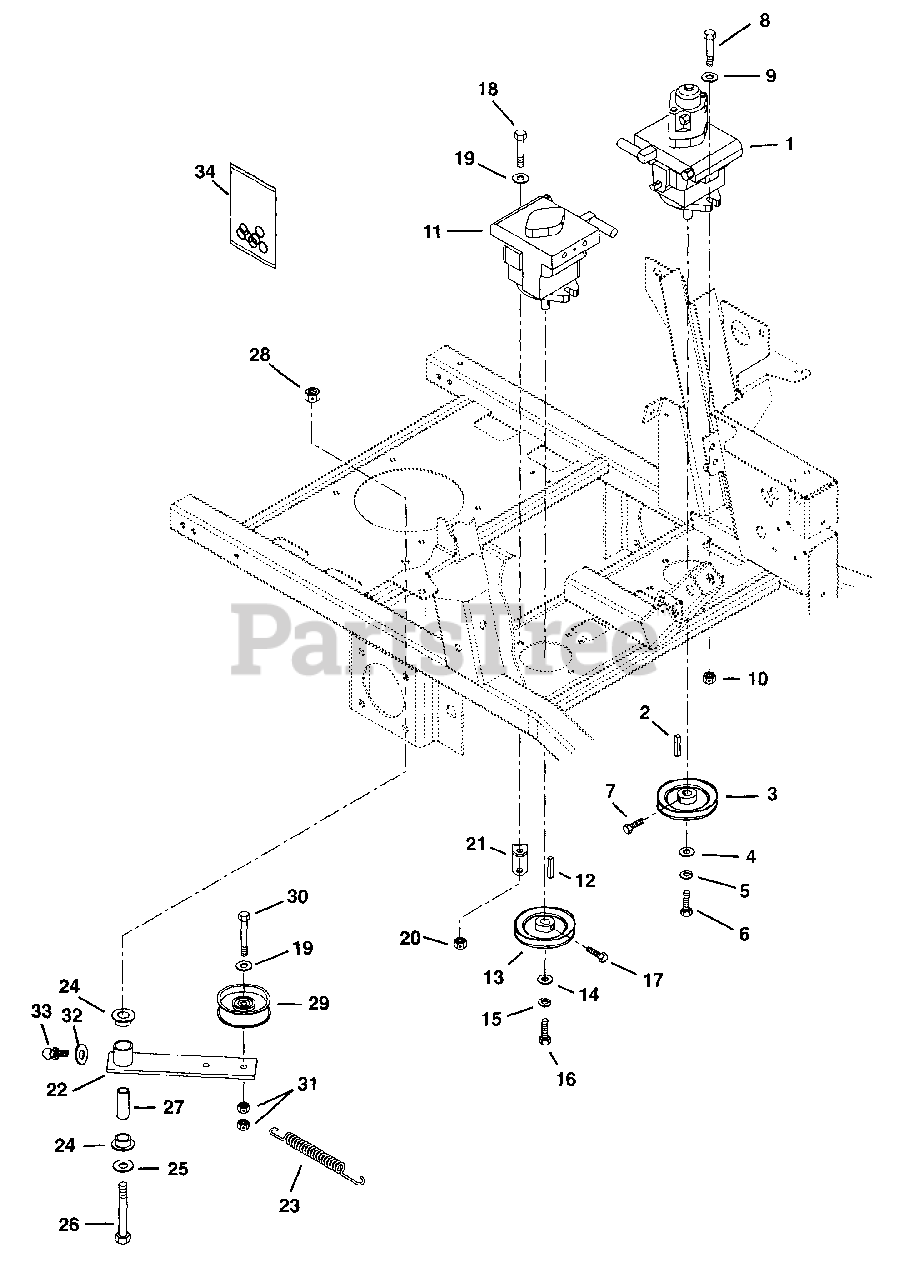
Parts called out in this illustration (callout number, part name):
1	Hydrostat BDP with Auxiliary
2	Key-Straight 5mm x 25mm x 5mm
3	Sheave 4.0 x .199
4	Washer-Flat-Steel .25 x 1.0 x .048
5	Washer-Locking .25 x .062
6	Bolt-Hex M6 x 1.0 x 12
7	Bolt-Hex .25-20 x .50 Grade 5
8	Bolt-Hex .38-16 x 1.25 Grade 5
9	Washer-Flat-Steel .390 x .75 x .125
10	Nut-Locking-Center .38-16
11	Variable-Displace Pump
12	Key-Straight 5mm x 25mm x 5mm
13	Sheave 4.0 x .199
14	Washer-Flat-Steel .25 x 1.0 x .048
15	Washer-Locking .25 x .062
16	Bolt-Hex M6 x 1.0 x 12
17	Bolt-Hex .25-20 x .50 Grade 5
18	Bolt-Hex .38-16 x 1.25 Grade 5
19	Washer-Flat-Steel .390 x .75 x .125
20	Nut-Locking-Center .38-16
21	Anchor-Spring-Idler
22	Arm-Ground Drive Idler
23	Spring-Tension .120 x .845 x 6.500
24	Bushing-Flange .762 x 1.0 x .580 x 1.48
25	Washer-Flat-Steel .531 x 1.06 x .095
26	Bolt-Hex .50-13 x 3.00 Grade 5
27	Bushing-Steel .560 x .745 x 2.04
28	Nut-Locking-Center .50-13
29	Assembly-Idler Pulley
30	Bolt-Hex .38-16 x 2.25 Grade 5
31	Nut-Locking-Center .38-16
32	Washer-Flat-Steel .265 x .50 x .087
33	Fitting-Lube .25-28 x .256
34	Kit-Pump Seal
